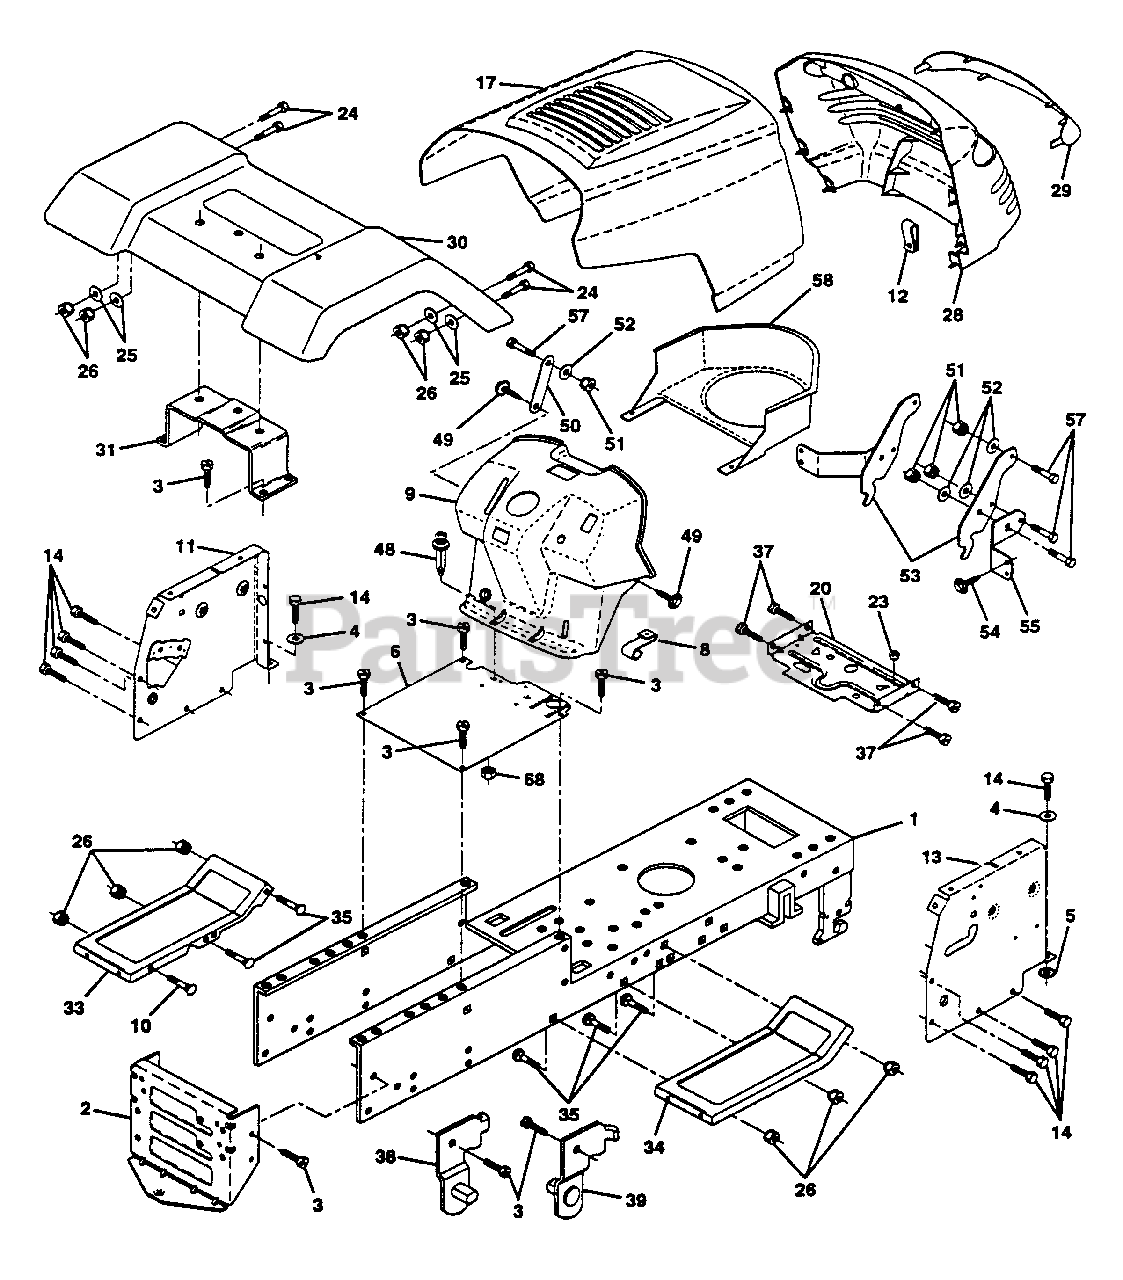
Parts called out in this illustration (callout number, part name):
1	Chassis Weldment 11 ga
2	Drawbar, Stretch
3	Screw Thdrol 3/8-16x3/4 Ty-tt
4	Washer 13/32 x 3/4 x 16 Ga.
5	Washer Lock Ext. Tooth 3/8
6	Saddle LT Fender Shift
8	Clip Insulator.406 Mtg Hole
9	Dash Private Label
10	Bolt Carriage 3/8-16 x 1
11	Panel Pnt Dash Lh
12	Clip Tinnerman Grille PAL
13	Panel Dash Rh Weldment
14	Screw Thdrol 3/8-16x1/2 Ty-tt
17	Hood Paint Steel Private Label
20	Support Battery
24	Bolt Fin Hex 3/8-16unc X 1 Gr. 5
25	Washer 13/32 X 13/16 X 12 Ga
26	Nut Lock Hex W/Ins 3/8-16 Unc
28	Grille Private Label
29	Lens Grille Private Label
30	Fender Pnt
31	Bracket Pnt Fender
33	Footrest Pnt Lh
34	Footrest Pnt Rh
35	Bolt Rdhd Sht Sqnk 3/8-16 X3/4
37	Screw Thdrol 5/16-18 X3/4
38	Bracket, Asm. Pivot, L.H., Mower Rear
39	Bracket, Asm. Pivot, R.H., Mower Rear
48	Rivet Push Plate D Plastick Blk
49	Screw Hexwsh. Thdrol 1/4-20 x 3/4
51	Nut Lock Hex W/Ins 1/4-20
52	Washer 9/32 x 7/8 x 16 Ga.
53	Hinge Pickoff Hood
54	Screw Lock Spider #8 x 7/8
55	Bracket, Grill
57	Bolt Hex 1/4-20 x 3/4
58	Air Duct P/L
68	Nut Keps Hex 1/4-20
